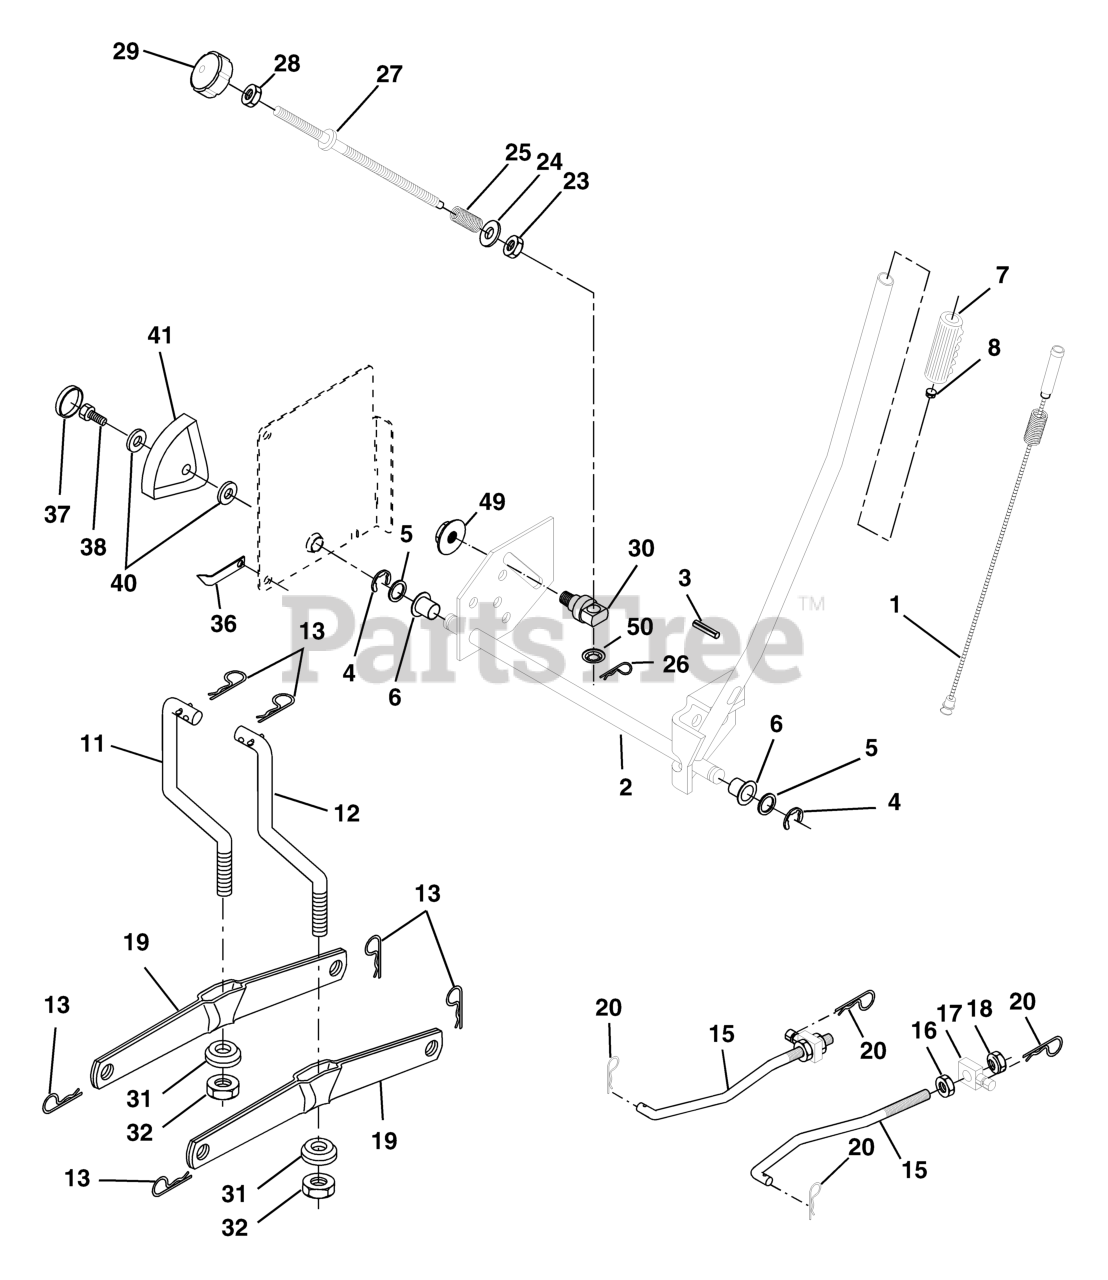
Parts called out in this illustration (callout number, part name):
1	WIRE ASM INNER W/ PLUNGER LT
2	SHAFT ASM R HANDLE
3	PIN GROOVE.
4	RETAINING RING LT
6	BEARING.NYLON
7	GRIP HANDLE
8	PLUNGER BUT KIT
11	LINK
12	LINK
13	RETAINER-SPRNG RB
15	LINK FRONT
16	NUT.HEX.JAM.1/2-13
17	TRUNION
18	NUT.LK.W/WSH.1/2.
19	ARM.REAR.SUSPENSION
20	SPRING RETAINER
25	SPRING**
26	RETAINER CLIP
27	ROD ADJ LIFT
28	NUT
29	KNOB INF 3/8-16
31	BEARING PIVOT
32	NUT CROWNLOCK 3/8-24
36	POINTER, HEIGHT INDICATOR(2 2)
38	SCREW 5/16-18X1
41	HEIGHT INDICATOR
49	NUT
50	NUT PUSH M
51	RETAINER-SPRNG RB
